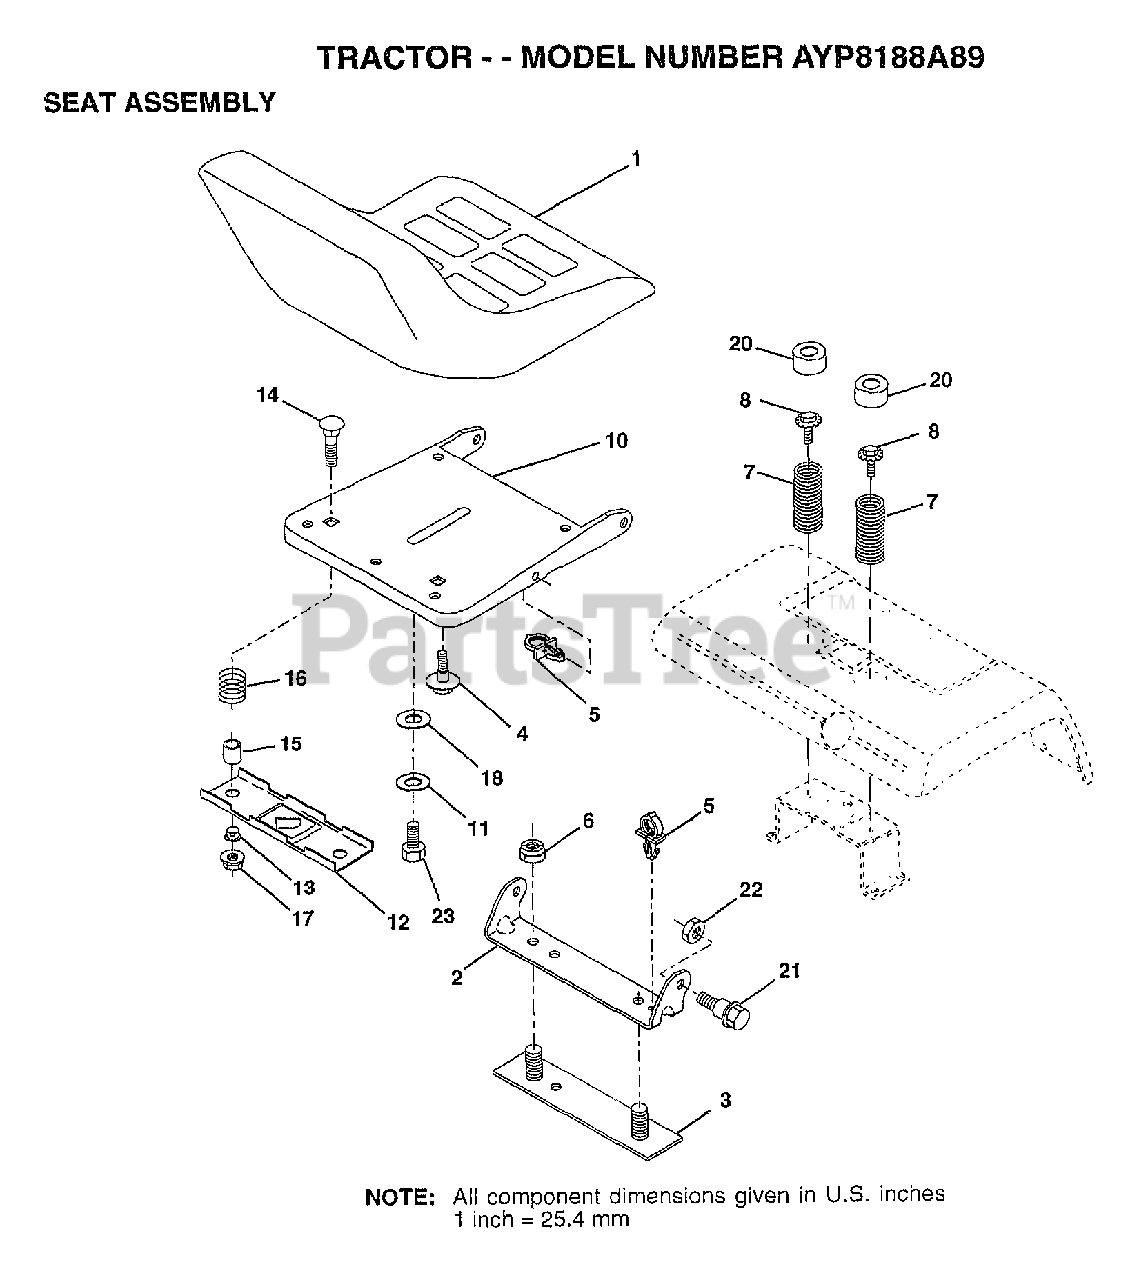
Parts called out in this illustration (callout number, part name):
1	SEAT.2400/1416.BK
2	BRACKET PVT SEAT
3	STRAP ASM FENDER
4	"BOLT,SHOULDER"
5	CLIP.PUSH-IN.HING
7	SPRING COMPRESSIO
8	BOLT.5/16-18.UNC
10	PAN-SEAT
11	LOCKWASHER
12	BRKT SWITCH
13	BUSHING
14	BOLT-RD HD SQ NK
15	SPLIT SPACER
16	SPRING
18	WASHER
20	CAP SPRING
21	"BOLT,SHOULDER"
23	BOLT
